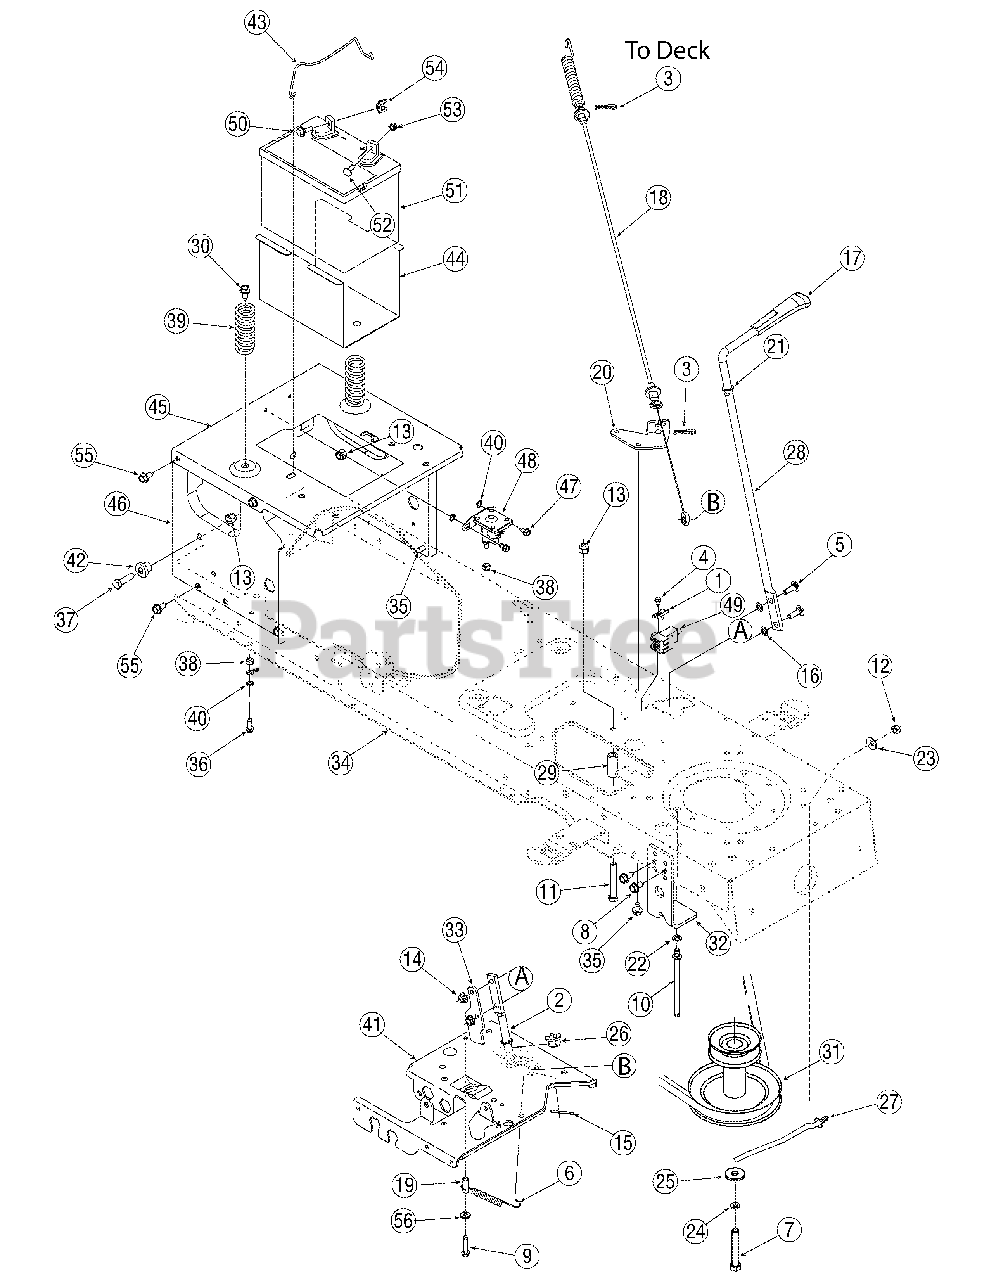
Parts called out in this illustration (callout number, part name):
1	Plate, Switch
2	Lever Assembly, Engagement
3	Click Pin
4	Screw, #10-16, 0.500
5	Screw, Carriage, 5/16-18, 1.00
6	Extension Spring, .38 OD x 3.9 Lg
7	Screw, 7/16-20, 2.75 46" Deck
7	Screw, 7/16-20, 3.25 42" Deck
8	Screw, 5/16-12, 0.750
9	Screw, 1/4-20 x 1.50
10	Pin, Belt Guard, 5/16 x 5.80
11	Screw, 3/8-16 x 2.25
12	Nut, Flange Lock, 5/16-18, GrF
13	Nut, Flange Lock, 3/8-16, GrF
14	Nut, Flange Lock, 5/16-18, Gr5
15	Pin, Cotter, 1/8 x 1.00
16	Nut, Speed, .3125 ID
17	Knob, PTO
18	Deck Engagement Cable
19	Spacer, .260 x .372 x 1.030 Lg.
22	Washer, Lock, 5/16
23	Washer, Bell, .340 x .872 x .060
24	Washer, Lock, 7/16
25	Washer, Flat, .450 x1.250 x.164
26	Bearing, Flange, Hex Split .500 ID
27	Keeper Rod, Belt
28	Engagement Handle, Deck
29	Spacer, .385 ID x .635 OD x 1.54
30	Screw, 5/16-18 x .750
31	Pulley, Engine, 42" Deck
31	Pulley, Engine, 46" Deck
36	Screw, 1/4-20, 0.750
37	Screw, 3/8-16, 1.25, Gr5
38	Nut, Flange Lock, 1/4-20, GrF
39	Spring, Compr., 1.28 OD x 3.125
40	Washer, Lock, 1/4, External
42	Spacer, Shoulder, .38 x 1.0 x .70
43	Hold Rod, Battery
48	Solenoid, 12V, 100 Amp
49	Switch, Interlock
50	Screw, Shoulder, .250 x .150
51	Battery, 190 CCA
51	Battery, 235 CCA
52	Hex Head Flange Screw
53	Nut, Sems, 1/4-20
54	Nut, Wing, 1/4-20
55	Screw, 5/16-18 x 0.625
56	Washer, Flat, .28 x .74 x .063
